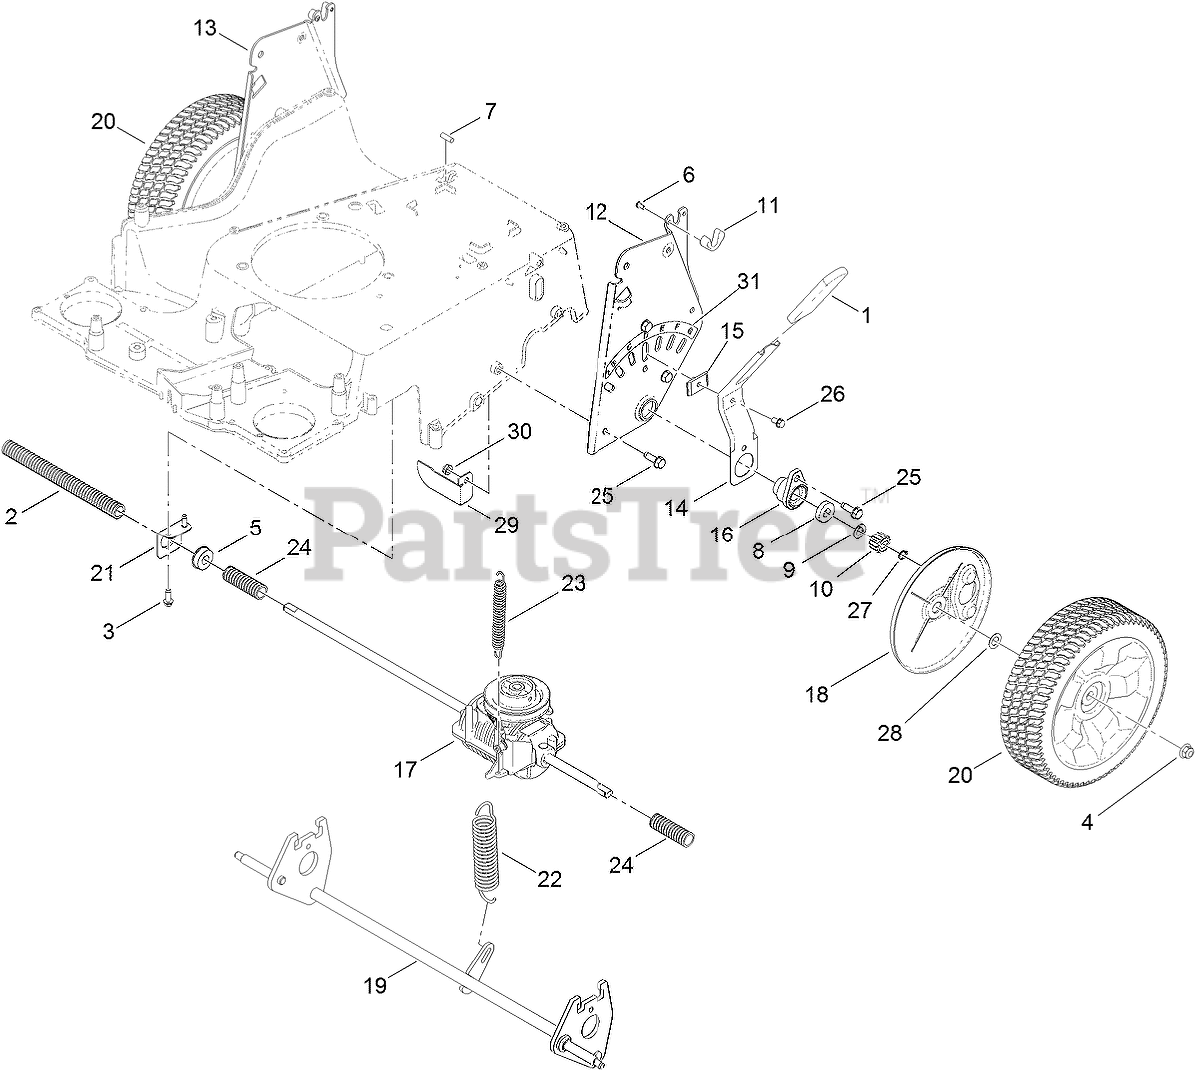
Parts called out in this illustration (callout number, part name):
1	GRIP-LEVER, LIFT
2	CONDUIT-CONVOLUTED
3	SCREW-HWHTF
4	NUT-HF, NI
5	BEARING-BALL
6	Screw-PPH
7	PIN-STOP
8	BEARING-BALL
9	WASHER-THRUST
10	GEAR-PINION, 15T
11	ANCHOR-BAG
12	PLATE-HOC, LH
13	PLATE-HOC, RH
14	ARM-SPRING, REAR
15	KEY-SPRINGARM
16	RETAINER-BEARING
17	TRANSMISSION-MSV2
18	COVER-GEAR
19	AXLE-REAR
20	10 INCH WHEEL GEAR ASM
21	MOUNT-BEARING
22	SPRING-EXTENSION
23	SPRING-EXTENSION
24	CONDUIT-CONVOLUTED
25	SCREW-HWHTF
26	SCREW-HWH
27	RING-RETAINING
28	WASHER-PLAIN
29	BRACKET-STOP
30	NUT-LOCK, NI
31	DECAL-HOC, REAR
